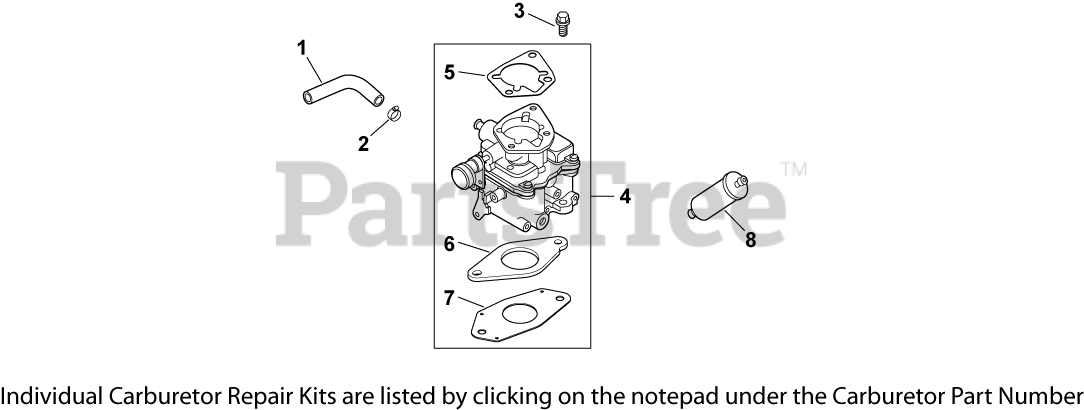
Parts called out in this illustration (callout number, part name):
1	HOSE,LW PERM.FUEL 24.00"-USE 25 111 81-S
2	CLAMP, HOSE (KM)-USE 25 237 31-S
3	SCREW, FLG M6X1.0X25
4	KIT, CARBURETOR W/GASKETS USE 24 853 257-S
5	GASKET, AIR CLEANER BASE
6	GASKET, CARBURETOR
7	GASKET, CARBURETOR
8	FILTER, FUEL
